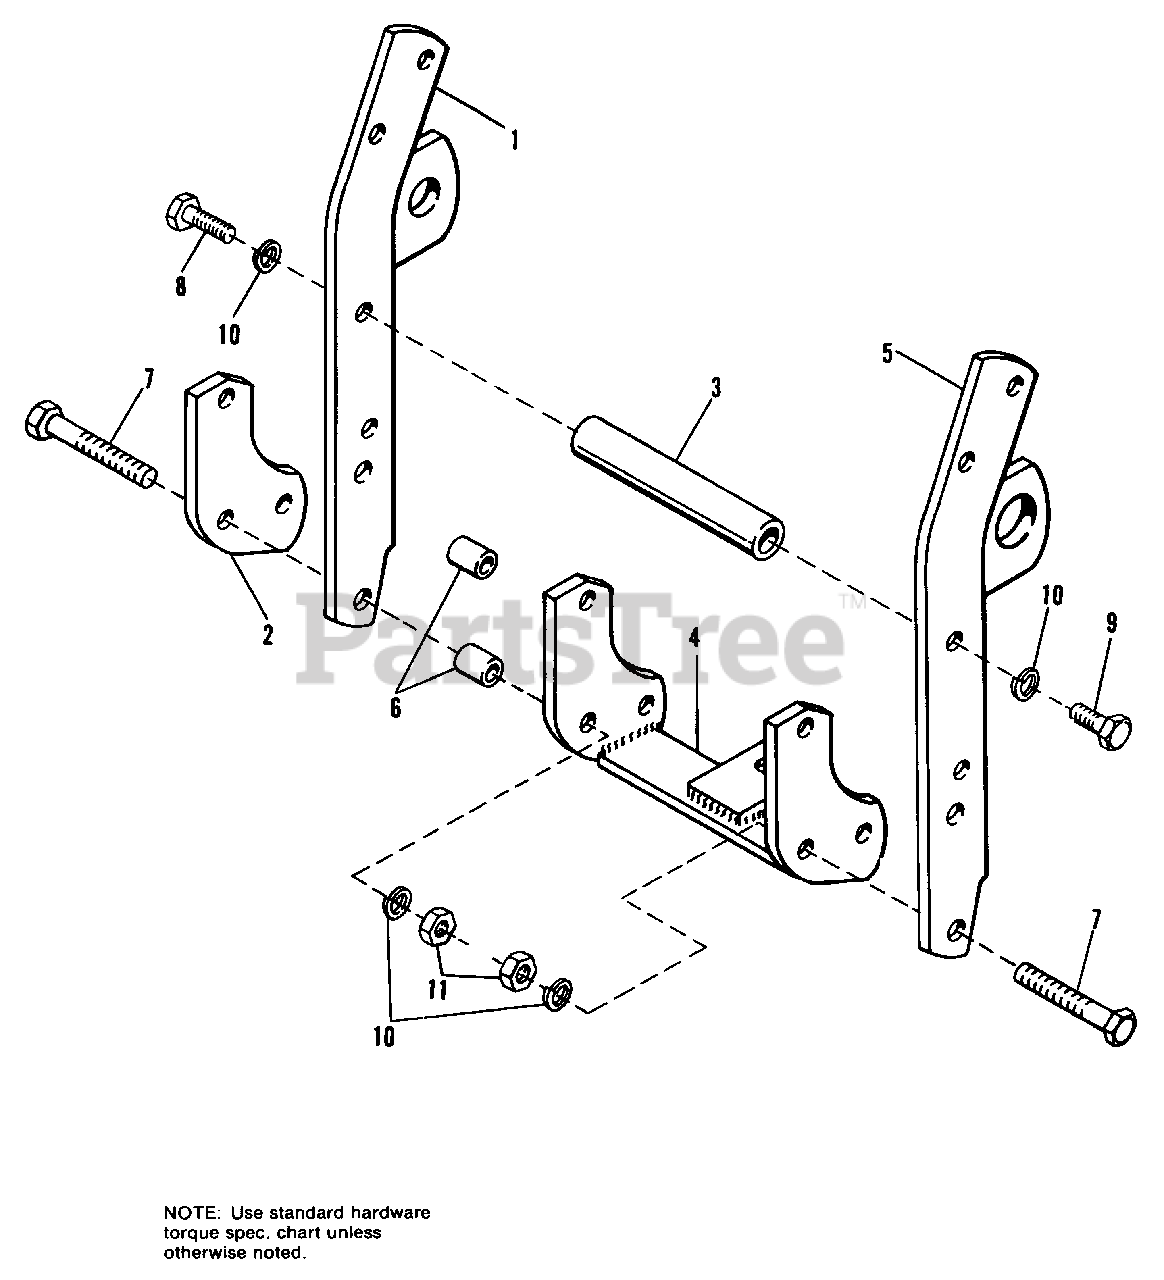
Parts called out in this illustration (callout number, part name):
1	BAR ASSY., Upright, R.H.
4	BAR ASSY., Draw
5	BAR ASSY., Upright, L.H.
7	CAPSCREW, Hex, 7/16-14 x 2-3/4
8	CAPSCREW, Hex, 7/16-14 x 1-3/4
9	CAPSCREW, Hex, 7/16-14 x 1-1 /4
10	LOCKWASHER, 7/16
11	NUT, Hex, 7/16-14
